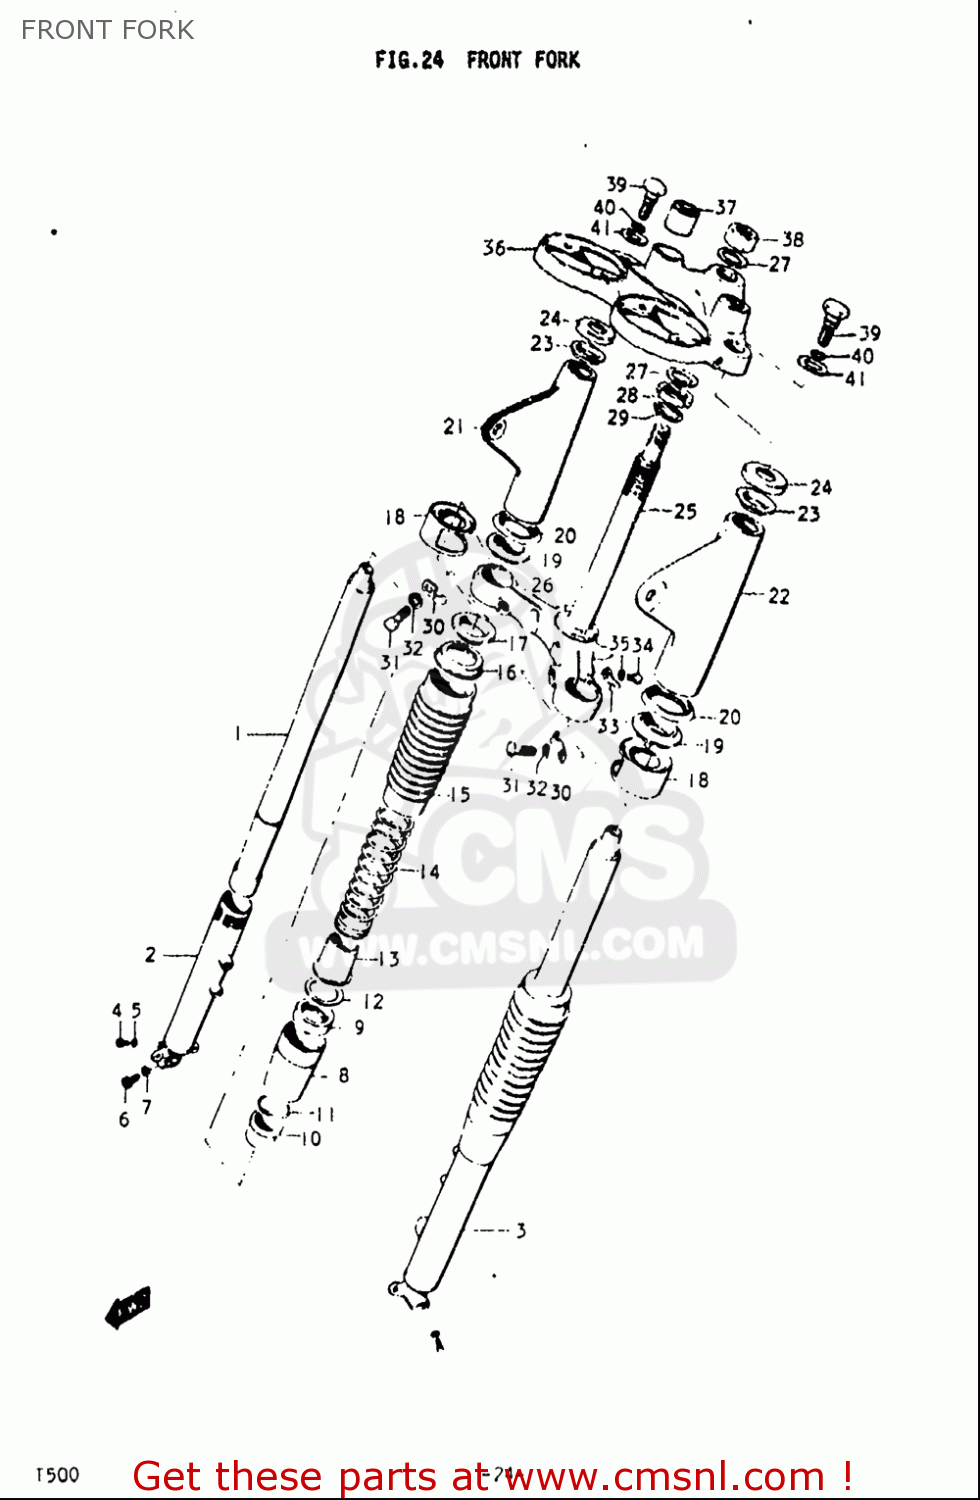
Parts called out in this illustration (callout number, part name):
4	OIL DRAIN PLUG
5	GASKET,DRAIN,PLUG (NAS)
6	BOLT
7	WASHER,LOCK
9	SEAL,OIL
12	WASHER
15	BOOT,SPRING COVER
30	CLIP,SPEEDOMETER CABLE
32	WASHER,LOCK
33	CLIP,BRAKE CABLE
34	SCREW
35	WASHER,LOCK
38	NUT
41	WASHER
